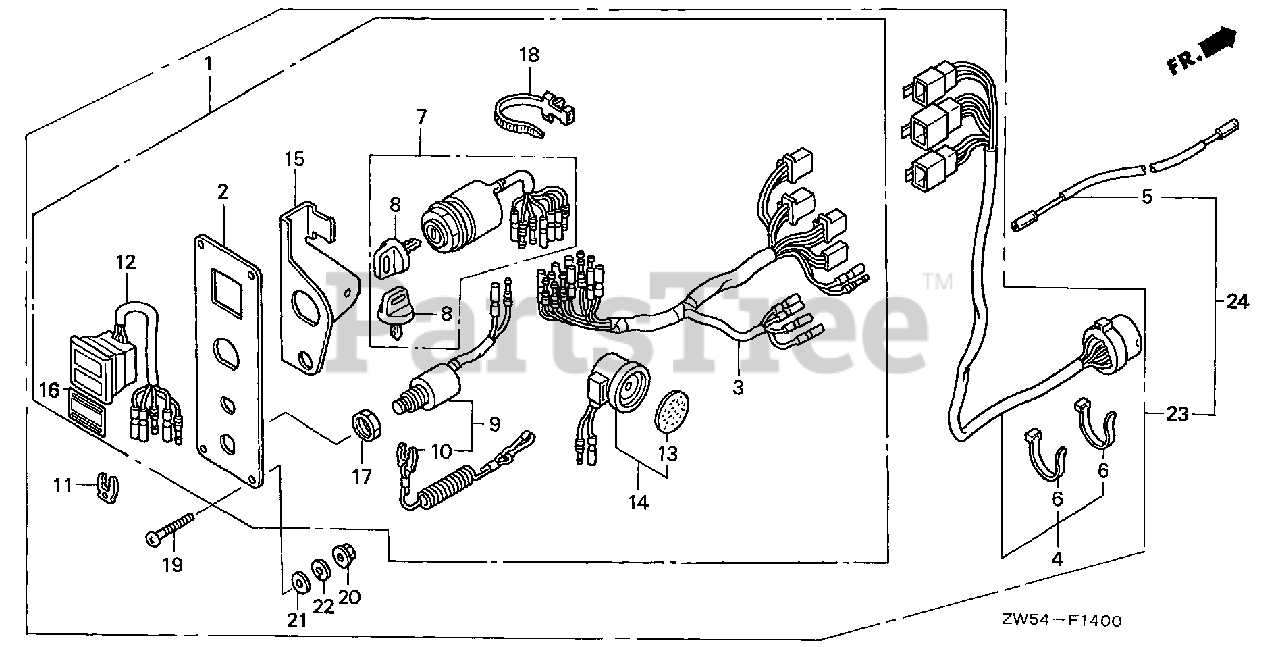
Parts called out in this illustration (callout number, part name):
1	PANEL ASSY., CONTROL (2-LED)
2	PANEL, CONTROL
3	HARNESS ASSY., SWITCH PANEL
4	CABLE ASSY., SWITCH PANEL Use up to Frame SN 1300028.
4	CABLE ASSY., SWITCH PANEL Use from Frame SN 1300029.
5	WIRE ASSY., GROUND (BONDING) Use up to Frame SN 1300028.
6	TIE, CABLE (NATURAL 2.4X92) Use up to Frame SN 1300028.
6	TIE, CABLE (NATURAL 2.4X92) Use from Frame SN 1300029.
7	SWITCH ASSY., COMBINATION
8	KEY ASSY., COMBINATION SWITCH
9	SWITCH ASSY., EMERGENCY STOP
10	WIRE, EMERGENCY
11	CLIP, EMERGENCY LOCK
12	LAMP ASSY., INDICATION (2-LED)
13	PLATE, TURN SIGNAL BUZZER
14	BUZZER, WARNING
15	BRACKET, BUZZER
16	MARK, SWITCH PANEL
17	NUT, HEX. (16MM)
18	BAND, WIRE HARNESS (150MM) (NATURAL)
19	SCREW, PAN (5X40)
20	NUT, FLANGE (5MM)
21	WASHER, PLAIN (5MM)
22	WASHER, SPRING (5MM)
23	PANEL KIT, SWITCH (SINGLE)
24	PANEL KIT, SWITCH (DUAL)
